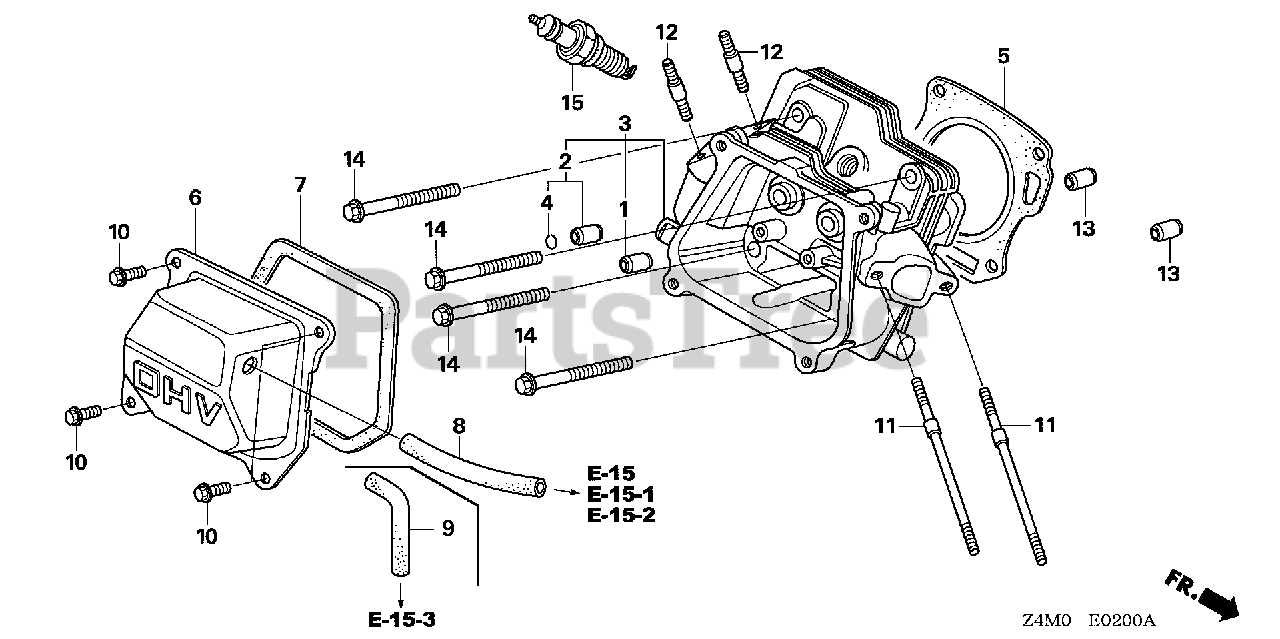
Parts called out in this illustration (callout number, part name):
1	GUIDE, VALVE (OS)
2	GUIDE, EX. VALVE (OS)
3	CYLINDER HEAD
4	CLIP, VALVE GUIDE
5	GASKET, CYLINDER HEAD
6	COVER, HEAD
7	GASKET, CYLINDER HEAD COVER
8	TUBE, BREATHER
10	BOLT, FLANGE (6X12) (CT200)
11	BOLT, STUD (6X109)
12	BOLT, STUD (8X32)
13	PIN A, DOWEL (10X16)
14	BOLT, FLANGE (8X60)
15	SPARK PLUG (BPR5ES) (Honda Code 7348428). (NA USE ALT:98079-56876)
15	SPARK PLUG (BPR6ES) (NGK)
